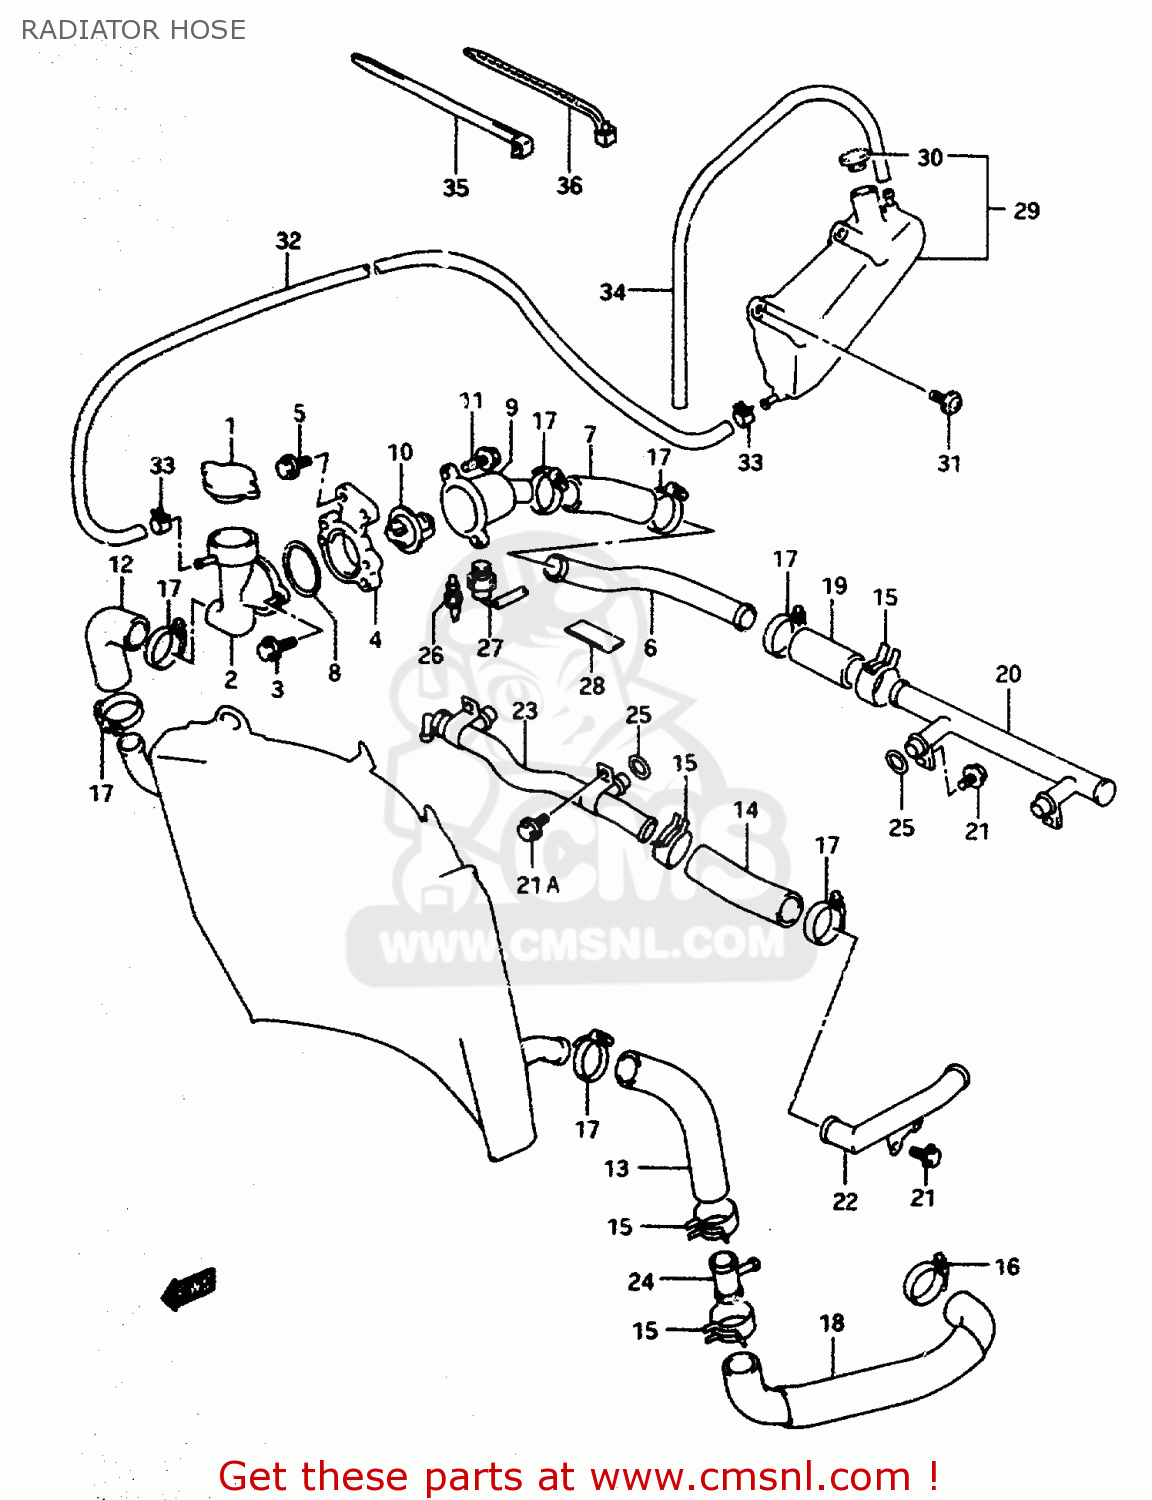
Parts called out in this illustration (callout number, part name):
1	CAP,RADIATOR
2	CONDUCTION,RADIATOR
3	BOLT
4	BRACKET,CONDUCTION
5	BOLT
6	PIPE,CONDUCTION INLET
7	HOSE,WATER
8	O RING(D:2.4,ID:43.2)
9	CONNECTOR,THERMOSTAT INLET
10	THERMOSTAT,WATER
11	BOLT
12	HOSE,RADIATOR INLET
13	HOSE,RDT OUTLE
14	HOSE,WATER
15	CLAMP
16	CLAMP
17	CLAMP
18	HOSE,WATER PUMP INLET
19	HOSE,HEAD OUTLET
20	PIPE,HEAD OUTLET
21	BOLT
21A	BOLT 6X12
22	PIPE
23	PIPE,CYLINDER INLET
24	UNION,HOSE JOINT
25	O RING(D:3.2,ID:17.8)
26	GAUGE ASSY,WATER TEMP
27	SWITCH COMP,RADIATOR FAN
28	CUSHION(50X42X2.0)
29	TANK ASSY,RESERVOIR
30	CAP,RESERVOIR TANK
31	SCREW(6X20)
32	HOSE,RESERVOIR TANK
33	CLIP
34	HOSE,RESERVOIR TANK
35	CLAMP
36	CLAMP L:165
